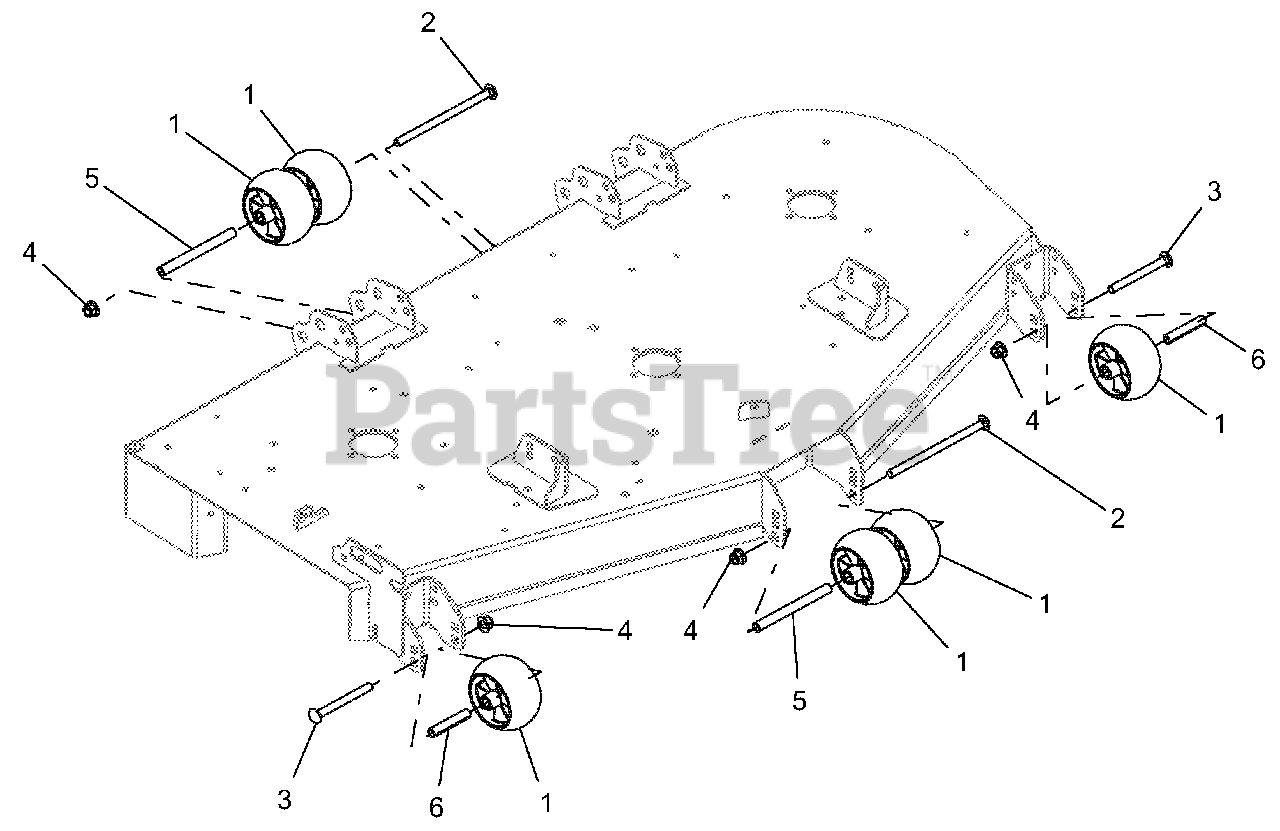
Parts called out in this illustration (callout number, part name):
1	ANTI-SCALP WHEEL - 5X3 CTR
2	BLT-RDHDSQNK .50-13X8.50 Y
3	BLT-RDHDSQNK .50-13X5.00 G5 YWZC
4	NUT-LK-NYL-FLG .50-13 YWZC
5	SPACER, .510 X .625 X 6.50
6	SPACER, .510X.625X3.35
